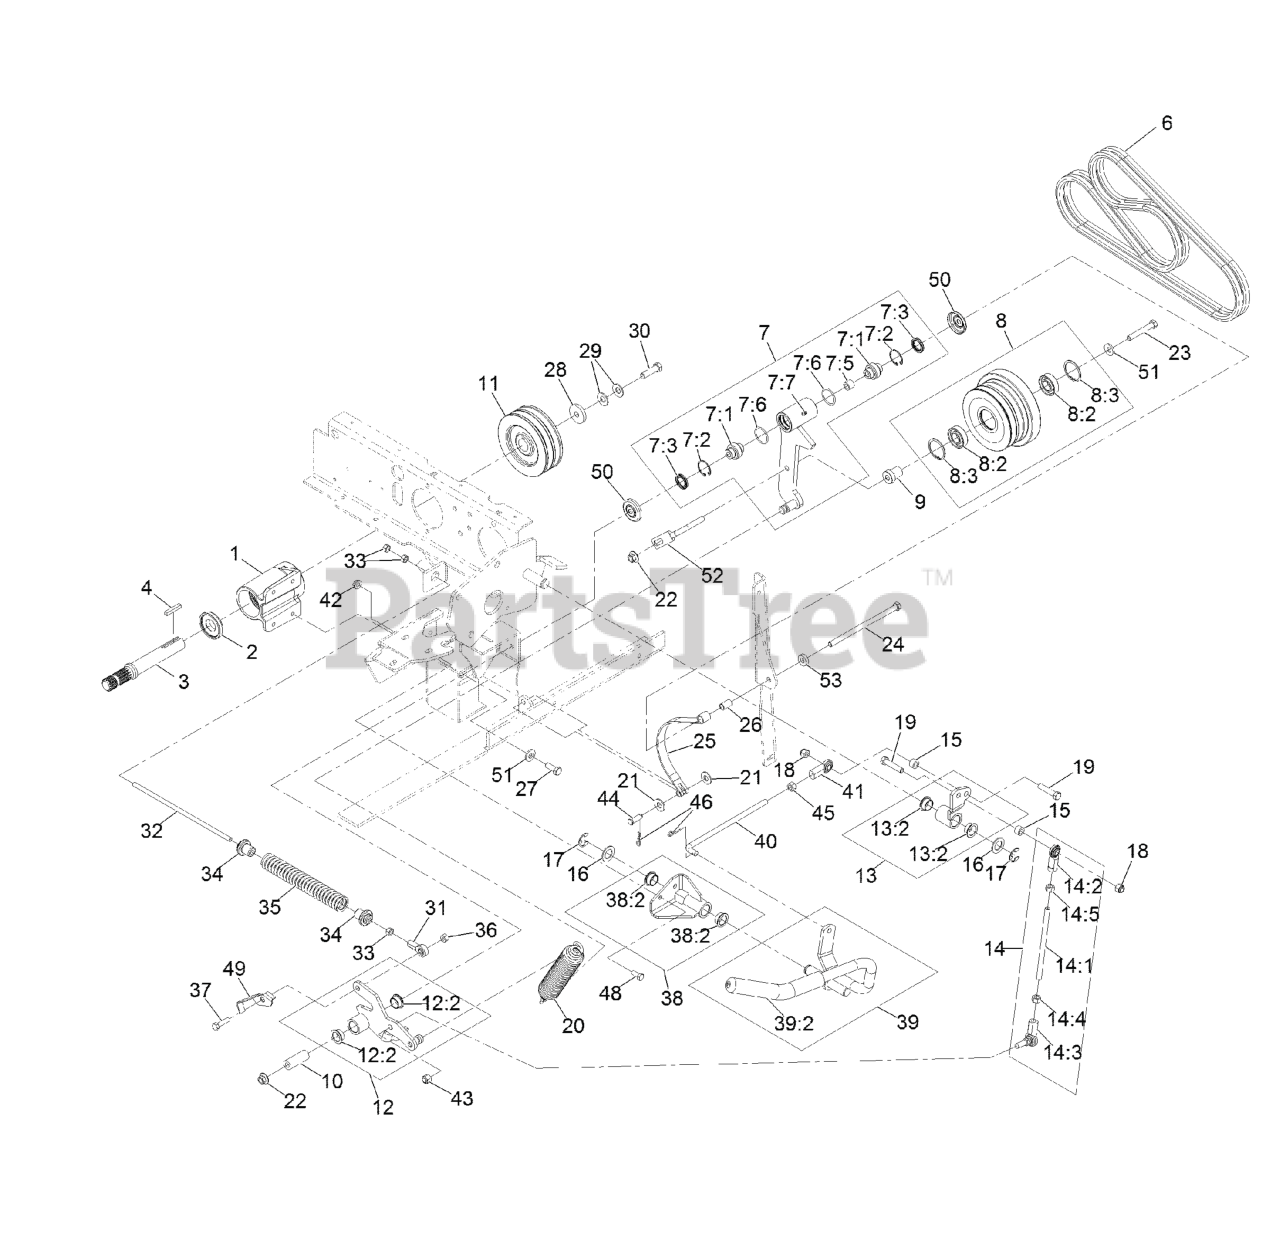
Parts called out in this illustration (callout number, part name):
2	SPACER-GUARD, BOTTOM
3	SHAFT-JACK
4	KEY-SQUARE
6	BELTS-MATCHED PAIR
7	IDLER PIVOT ASM
7:1	BEARING-SPHERICAL
7:2	RING-SNAP
7:3	SEAL-LIP, SINGLE
7:5	BUSHING-LEVER, LIFT
7:7	FITTING-GREASE
8	IDLER SHEAVE ASM
8:2	BEARING-BALL
8:3	RING-RETAINING
9	SPACER-IDLER
10	BUSHING
12	ARM ASM
12:2	BUSHING-BRONZE
13	ARM ASM
13:2	BUSHING-BRONZE
14	CLUTCH LINK ASM
14:1	ROD-LINKAGE
14:2	JOINT-BALL END, LH
14:3	BALLJOINT-RH
14:4	NUT-HEX
14:5	NUT-HEX, LH
18	NUT-LOCK, NI
19	SCREW-HH
20	SPRING-EXTENSION
21	WASHER-FLAT
23	SCREW-HH
24	SCREW-HH
25	BAND-BRAKE
27	SCREW-HH
28	WASHER-CLUTCH
29	WASHER-SPRING
30	SCREW-HH
31	BALLJOINT-RH
32	LINKAGE-ROD, PTO BRAKE
33	NUT-HEX
34	BUSHING-SPRING
35	SPRING-BRAKE
36	NUT-LOCK, NI
37	SCREW-HH
38	PIVOT ASM
38:2	BUSHING-BRONZE
39	PTO HANDLE ASM
39:2	GRIP-LEVER, CONTROL
40	LINK-HANDLE
41	JOINT-BALL, END
43	NUT-LOCK
44	PIN-CLEVIS
45	NUT-HEX
46	PIN-COTTER
48	SCREW-HH
49	SWITCH-FLAG
50	GUARD-TOP
51	WASHER-BELLEVILLE
52	GUIDE-BELT
53	SPACER
